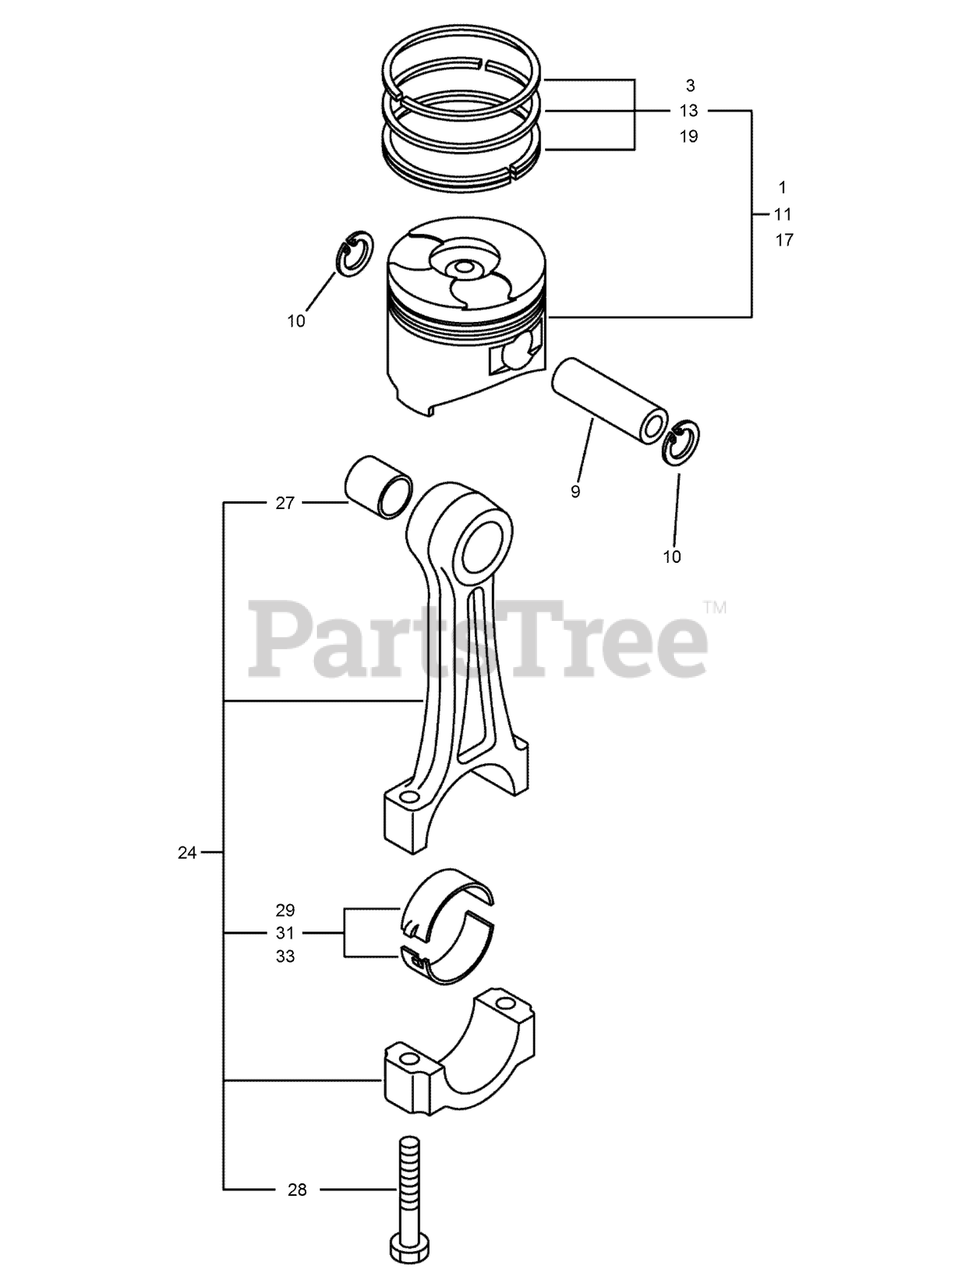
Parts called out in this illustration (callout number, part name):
1	PISTON W/RINGS
3	PISTON RING SET
9	PIN-PISTON
10	RING-SEEGER
11	PISTON W/RING (.25 O S)
13	RING SET (O S=0.25)
17	PISTON W/RING (.50 O S)
19	RING SET (O S=0.50)
24	CONNECTING ROD ASM
27	BUSHING-PIN, PISTON
28	BOLT-ROD, CONNECTING
29	BEARING-PIN, CRANK
31	BEARING ASM (0.25)
33	BEARING (0.50 U S)
